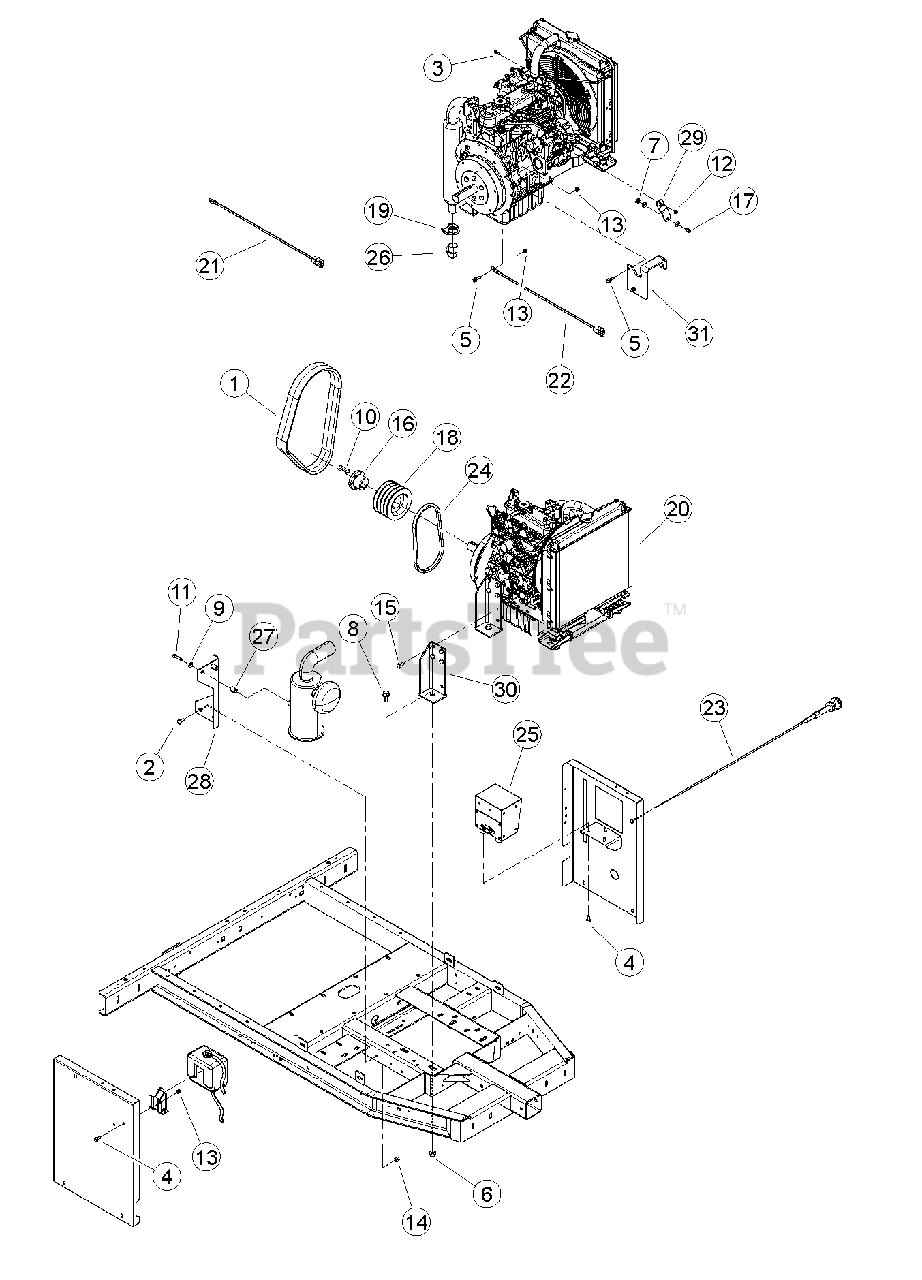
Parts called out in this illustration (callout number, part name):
1	BELT, 3RB48 ARAMID
2	BOLT, 3/8 X 1" GR5 CRG NC ZP
3	BOLT, 1/4-20 X 3/4 HWH GR5 CZP
4	BOLT, 5/16 X 3/4 FLANGE NC
5	BOLT, 5/16 X 1 FLANGE NC
6	NUT, 1/2-13 NYLOCK FLANGE
7	WASHER, 7/16" SAE FLAT ZP
8	BOLT, 1/2 -13 X 1-1/4 FLANGE NC
9	WASHER, 5/16" FLAT ZP
10	KEY, 3/8" SQ X 2" LG PLAIN
11	BOLT, M8 X 1.25 X 40 GR8.8 HCPS
12	NUT, 1/4-20 NYLOCK-FLANGE
13	NUT, 5/16-18 NYLOCK-FLANGE
14	NUT, 3/8-16 NYLOCK FLANGE
15	BOLT, M10 X 1.25 X 20 GR10.9 HEX HEAD ZP
16	BUSHING, SD 1-7/16"
17	CABLE, STOP - BOWDEN PIN # 6170
18	SHEAVE, 4B5.2 SD
19	CLAMP, 1-1/2" MUFFLER
20	ASSEMBLY, 28 HP KUBOTA DIESEL ENGINE
21	CABLE, 72" POSITIVE BATTERY
22	CABLE, 72" NEGATIVE BATTERY
23	CABLE, DIESEL THROTTLE 30 IN
24	BELT, BX30
25	CONTROLLER, DSE - KUBOTA
26	ELBOW, KUBOTA EXHAUST
27	SPACER .75 X .90
28	BRACKET, AIR-CLEANER MOUNT
29	STRIP, THROTTLE CONTROL
30	WELDMENT, ENGINE MOUNT
31	BRACKET, THROTTLE
